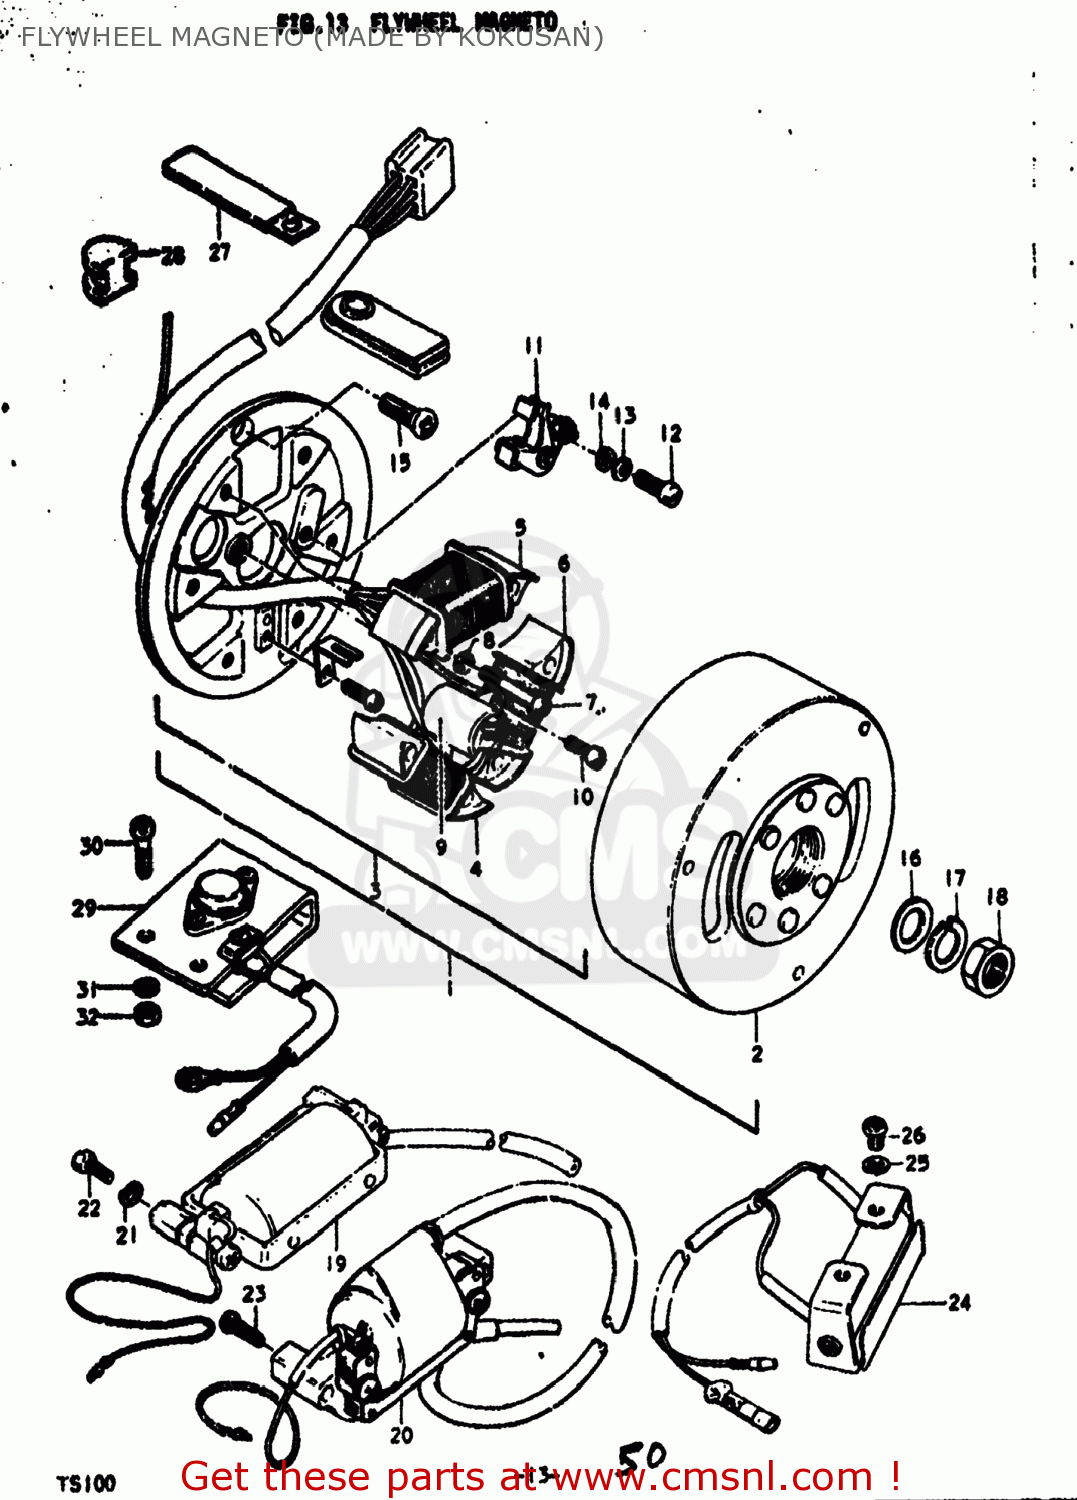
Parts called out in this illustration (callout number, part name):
1	MAGNETO ASSEMBLY
2	ROTOR ASSEMBLY
3	STATOR ASSEMBLY
4	COIL
5	COIL
6	COIL,LIGHTING
7	SCREW
8	LOCK WASHER
9	CONDENSER
10	SCREW
11	POINT ASSEMBLY,CONTACT
12	SCREW
13	LOCK WASHER
14	WASHER
15	SCREW
16	WASHER
17	LOCK WASHER
18	NUT (10MM)
19	COIL ASSEMBLY,IGNITION
20	COIL ASSEMBLY,IGNITION
21	LOCK WASHER
22	BOLT
23	SCREW
24	RESISTOR, MAGNETO
25	LOCK WASHER
26	SCREW
27	CLAMP
28	PLUG
29	REGULATOR ASSEMBLY
30	SCREW 6X12
31	WASHER
32	NUT
